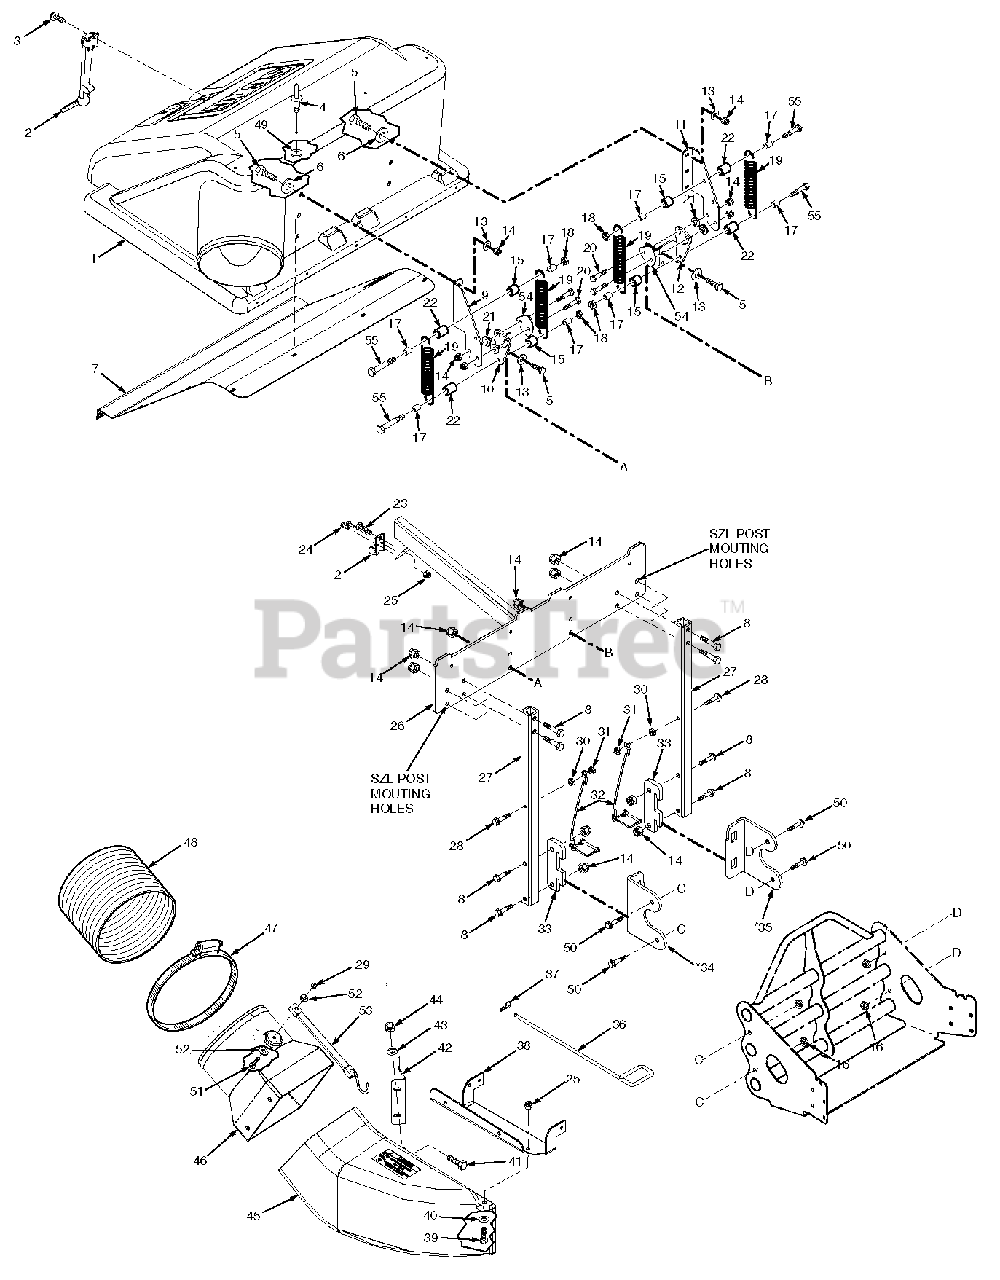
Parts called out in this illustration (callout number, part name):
1	Hood Assembly
2	Latch
3	Screw, #10-32 x 3/4"
3	Flatwasher, 3/8-.193 x .496 x .048
3	Nut, Elastic Stop #10-32
4	Pop Rivet, 3/16 x .652
5	Bolt, Hex Head 3/8-16 x 1-1/4"
6	Flatwasher, 3/8-.406 x 1.5 x 7 Ga.
7	Screen, GC Hood
8	Bolt, Hex Head 3/8-16 x 2-1/4"
9	Hinge, Upper RH
10	Hinge, Lower RH
11	Hinge, Upper LH
12	Hinge, Lower LH
13	Flatwasher, 3/8-391 x .938 x .105
14	Nut, Elastic Stop 3/8-16
15	Spacer
16	Nut, Serrated Flange 3/8-16
17	Sleeve
18	Nut, Center Lock 3/8-16
19	Spring
20	Bolt, Hex Head 3/8-16 x 1-1/2"
21	Bushing, Hopper Pivot
22	Spacer
23	Bolt, Hex Head 5/16-18 x 3/4"
24	Pop Rivet, 3/16 x .402
25	Nut, Elastic Stop 5/16-18
26	Frame Weldment, Bag Support
27	Tube, Grass Catcher Mount
28	Bolt, Hex Head 1/4-20 x 2"
29	Nut, Elastic Stop 1/4-20
30	Nut, Serrated Flange 1/4-20
31	Nut, Center Lock 1/4-20
32	Snap Pin Assembly w/Lanyard
33	Latch, GC
34	Bracket, GC Mount RH
35	Bracket, GC Mount LH
36	Latch Pin, GC Chute
37	Hair Pin Cotter
38	Bracket, GC Boot - 36" Deck
38	Bracket, GC Boot - 48", 52" & 61" Deck
39	Bolt, Hex Head 5/16-18 x 1"
40	Flatwasher, 5/16-.344 x .688 x .065
41	Bolt, Hex Head 1/4-20 x 1"
42	Baffle, Boot Deflector - 36" Deck
42	Baffle, Boot Deflector - 48" Deck
42	Baffle, Boot Deflector - 52" Deck
42	Baffle, Boot Deflector - 61" Deck
43	Flatwasher, 1/4-.312 x .750 x .065
44	Nut, Elastic Stop 1/4-20
45	Boot Assembly
46	Adapter w/Strap
47	Clamp, 8.62" Max Dia.
48	Hose. 8" x 56"
49	Flatwasher, 3/16-.196 x .469 x .048
50	Bolt, Hex Head 3/8-16 x 1"
51	Bolt, Hex Head 1/4-20 x 1-1/4"
52	Flatwasher, 1/4-.312 x .750 x .065
53	Rubber Strap
54	Guard, Hinge
55	Bolt, Hex Head 3/8-16 x 3-3/4"
